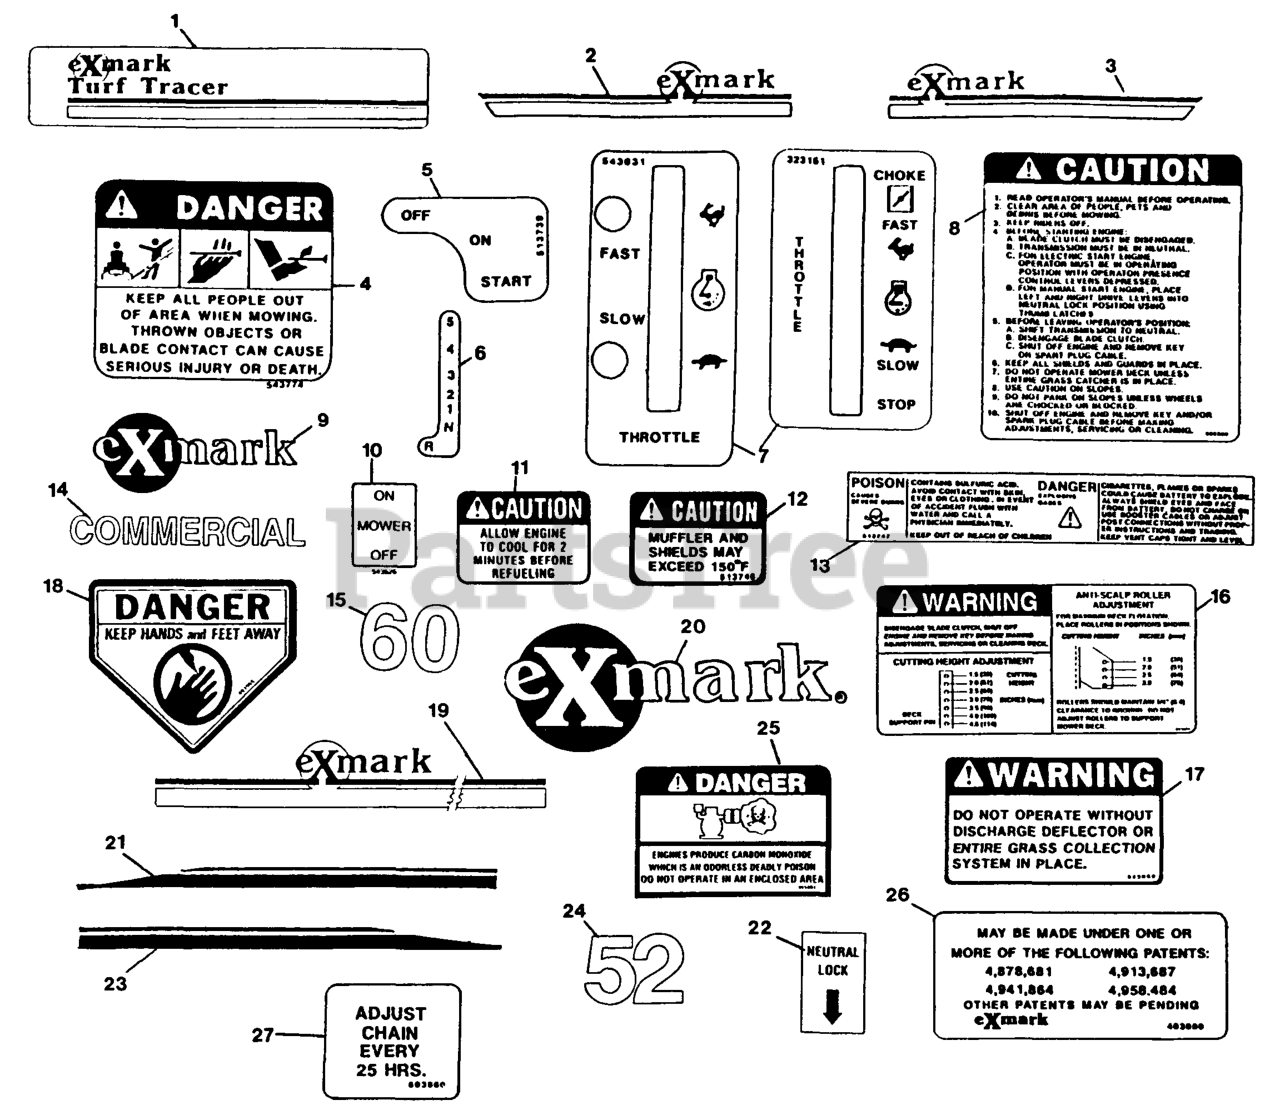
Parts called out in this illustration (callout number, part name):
4	DECAL-DANGER
10	DECAL-MOWER SWITCH
13	DECAL-BATTERY
18	DECAL-DANGER
22	DECAL,NEUTRAL LOCK
